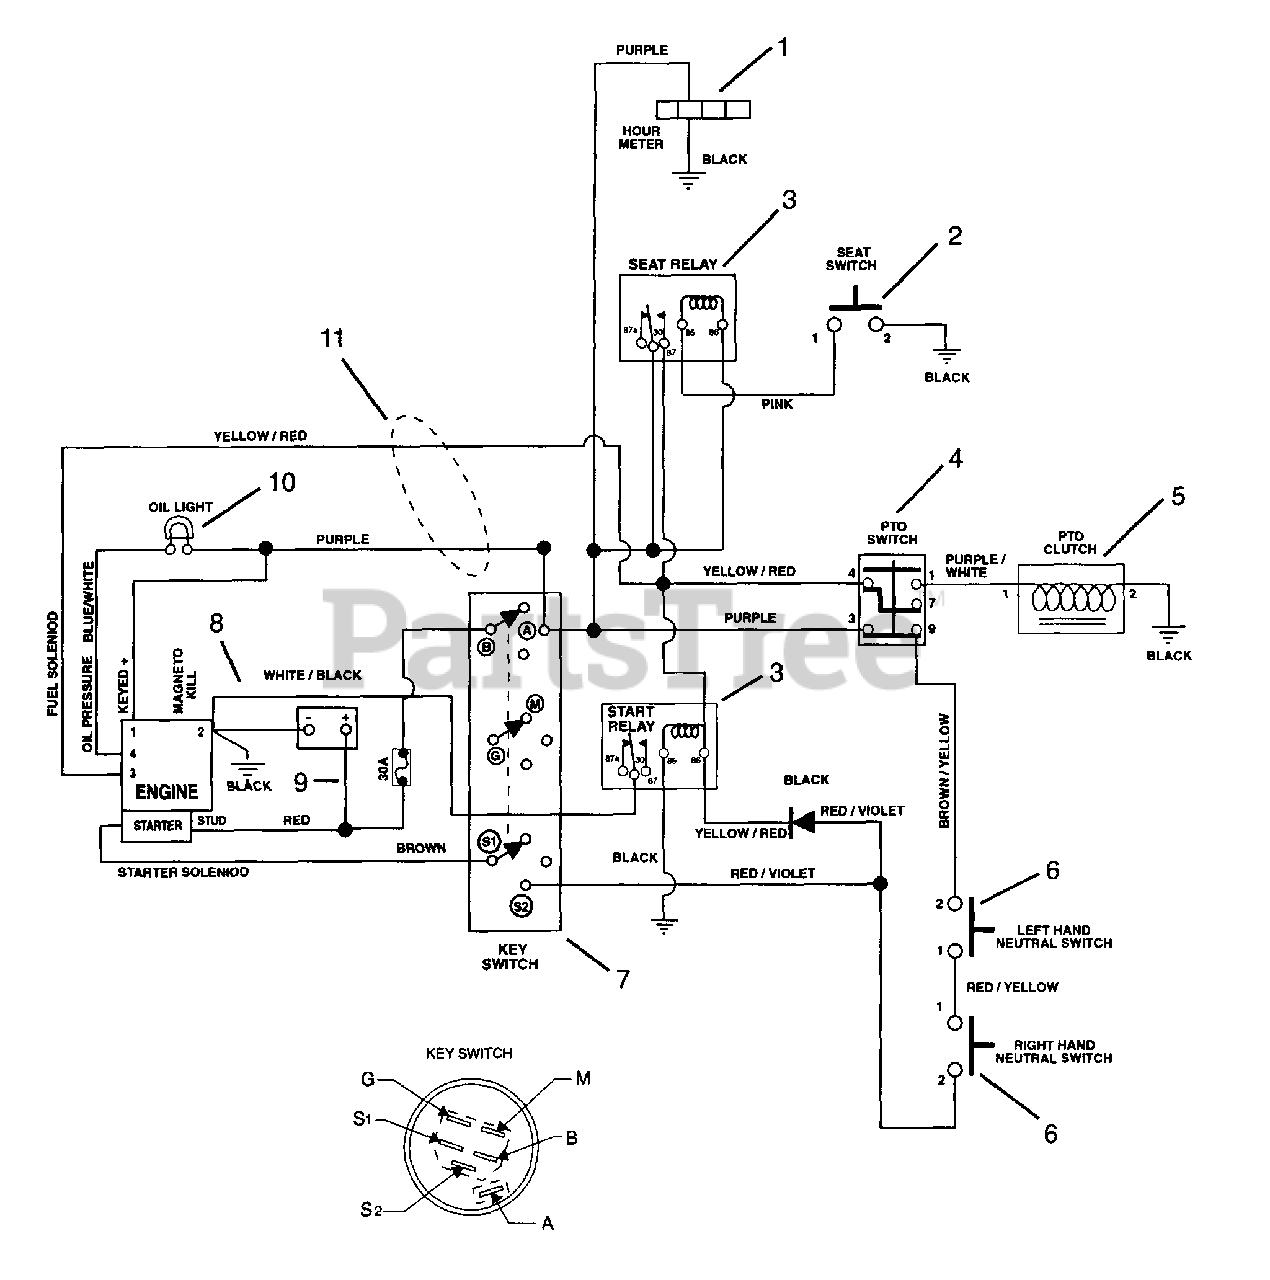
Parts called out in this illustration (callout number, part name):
1	Hour Meter
2	Switch-Seat
3	Relay
4	Switch, Clutch with Retainer Ring
5	Clutch, Electric - Warner
6	Switch - Neutral Start N.O.
7	Key Switch
8	Start Cable 22"
9	Cable, Negative Battery
10	Light, Indicator
11	Harness, Wiring 18 HP Kohler
